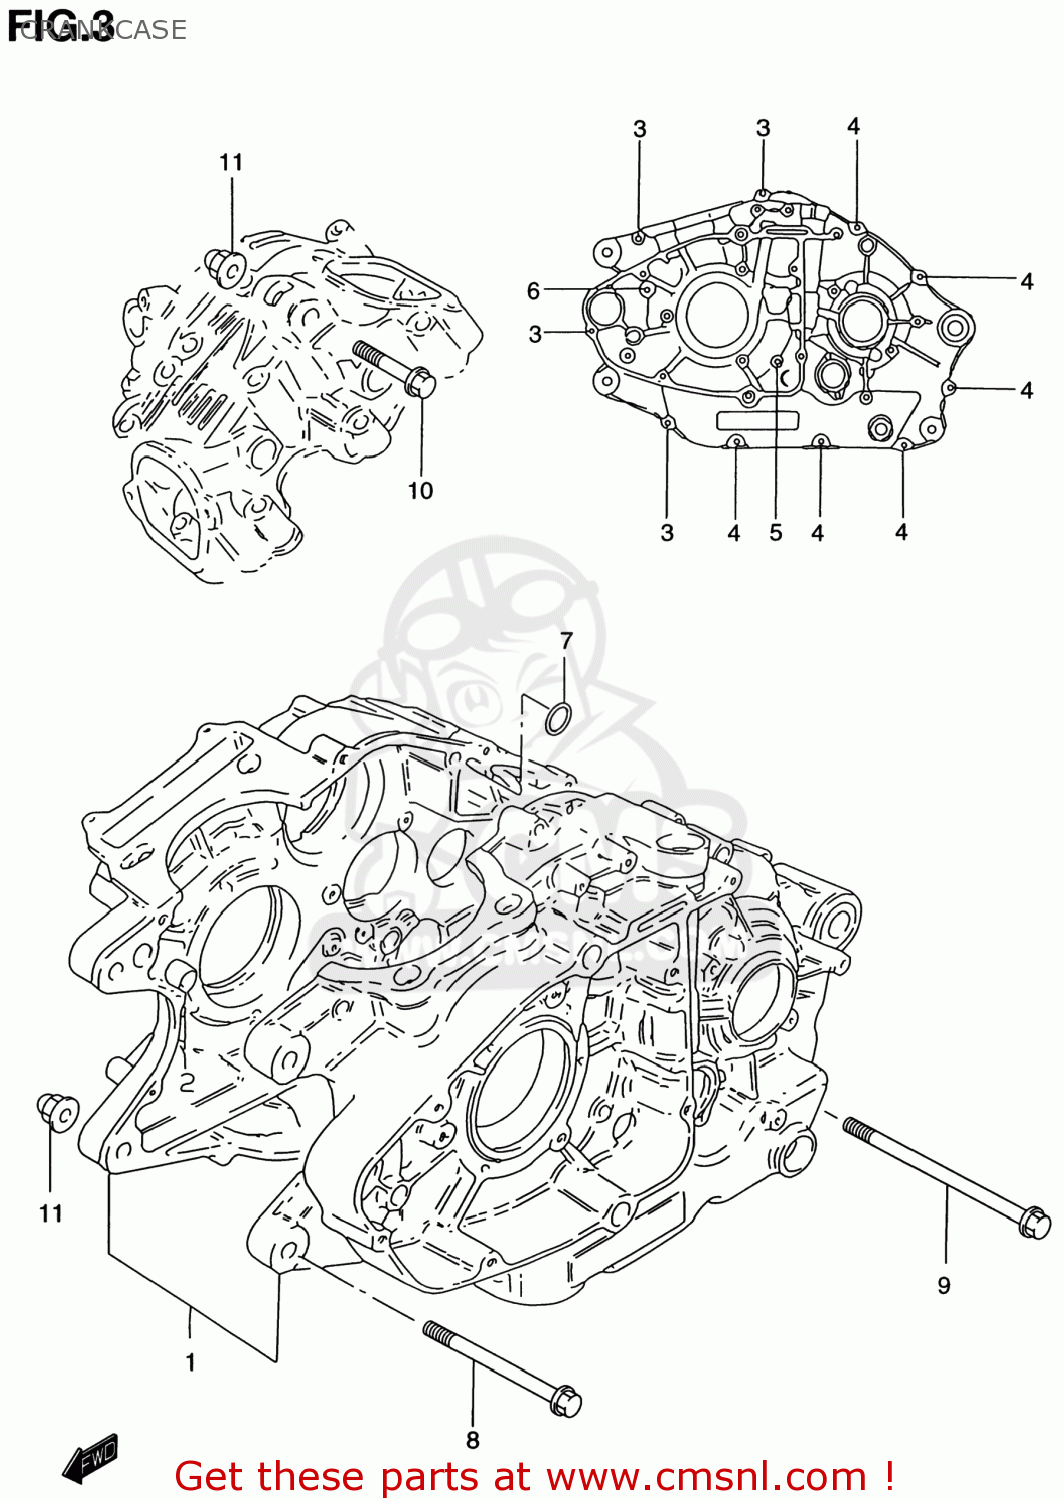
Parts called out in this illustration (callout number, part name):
1	CRANKCASE SET
2	PIN
3	BOLT
4	BOLT
5	BOLT
6	BOLT
7	O RING(D:1.9,ID:9.8)
8	BOLT(8X67)
9	BOLT(8X100)
10	BOLT(8X50)
11	NUT
